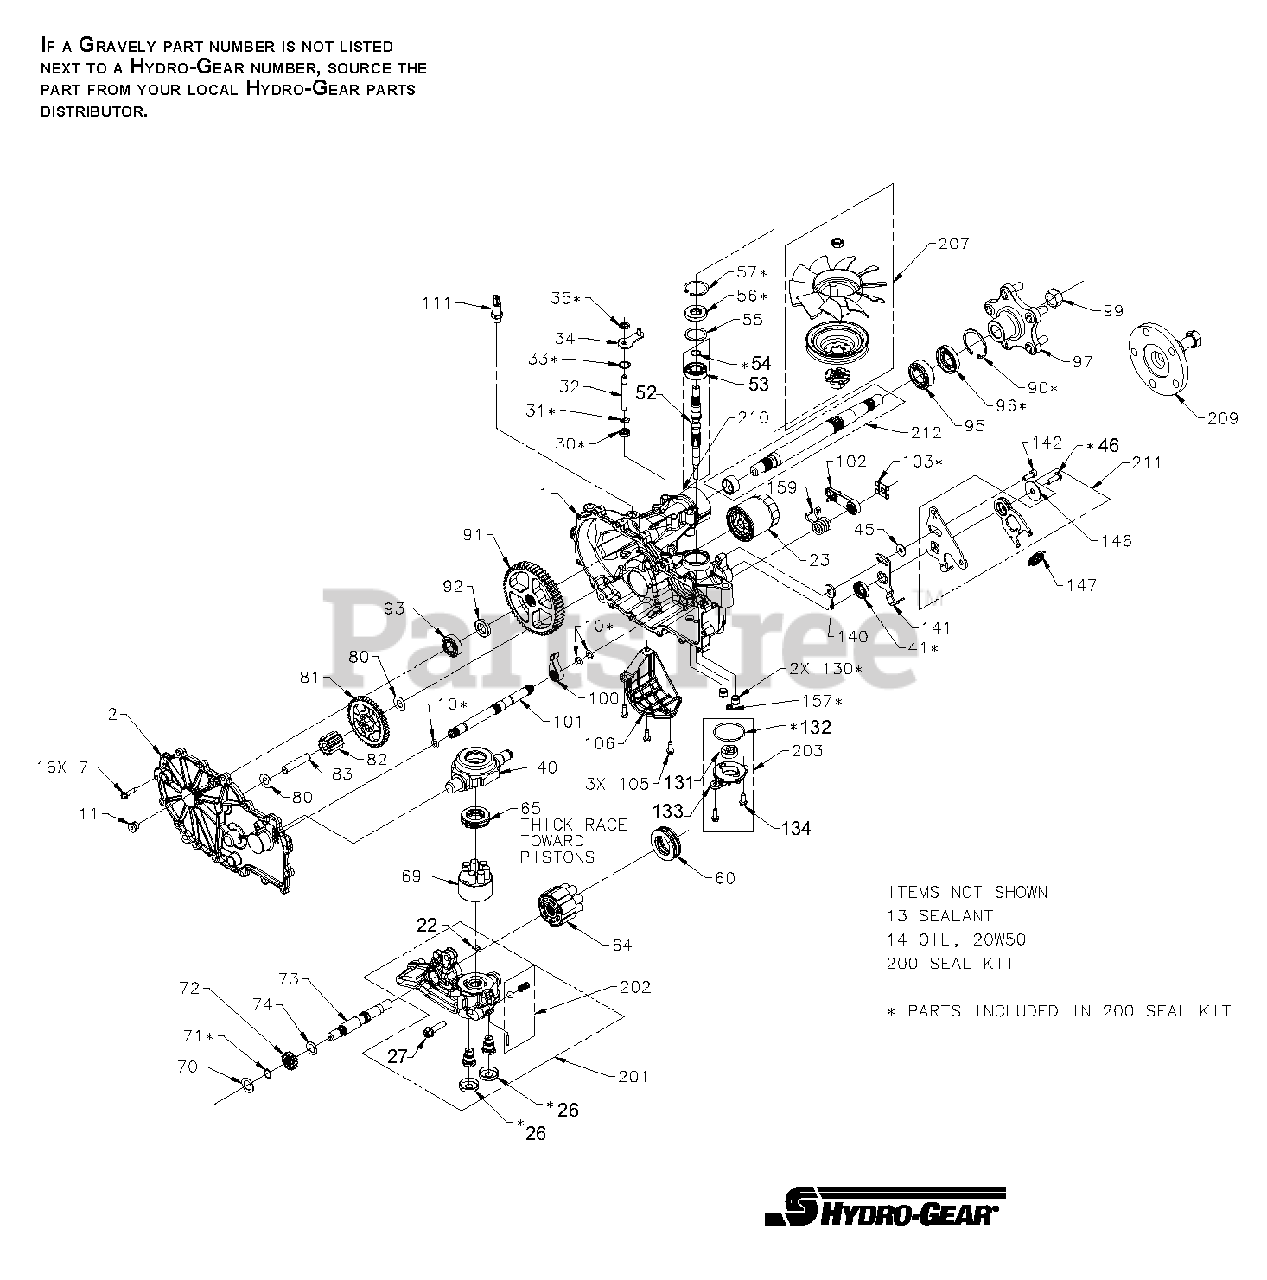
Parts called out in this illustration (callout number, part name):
7	HFHCS 1/4-20 X 1.25
11	PLUG, 9/16-18 (METAL)
22	PLATE, BYPASS
23	FILTER, OIL
30	SEAL, LIP .375 X .75 X .25
31	RING, RETENTION .375 EXTERNAL
33	RING, RETENTION .750 INTERNAL
35	RING, RETENTION .375 EXT
40	TRUNNION, SWASHPLATE
45	WASHER, .34 X .88 X .06
46	TWHCS 5/16-24 X 1.00
53	BEARING, BALL 17 X 40 X 12 OPEN 6203
55	WASHER, 1.23 X 1.56 X .04
56	SEAL, LIP 17 X 40 X 7
57	RING, RET 1.59 INT
65	BEARING, THRUST BALL 30 X 52 X 13
70	WASHER, .63 X 1.0 X .05
71	RING, RETAINING .625
74	WASHER, .72 X 1.16 X .04
80	WASHER, .5 X 1.0 X .03
83	JACK SHAFT
90	RING, RET 2.06 INT
95	BEARING, BALL 1.0 X 52 X 15 OPEN 6205M
96	SEAL, LIP 25 X 52 X 10 TC (GRAY)
99	NUT, HEX LOCK 3/4-16
105	HFHCS 1/4-20 X .75
131	ASSEMBLY, GEROTOR TANG X 1.15 X .39
134	HFHCS 1/4-20 X .75
142	SHCS 5/16-24 X 1 PATCH
146	WASHER, .343 X 1.5 X .062
NS	SEALANT
